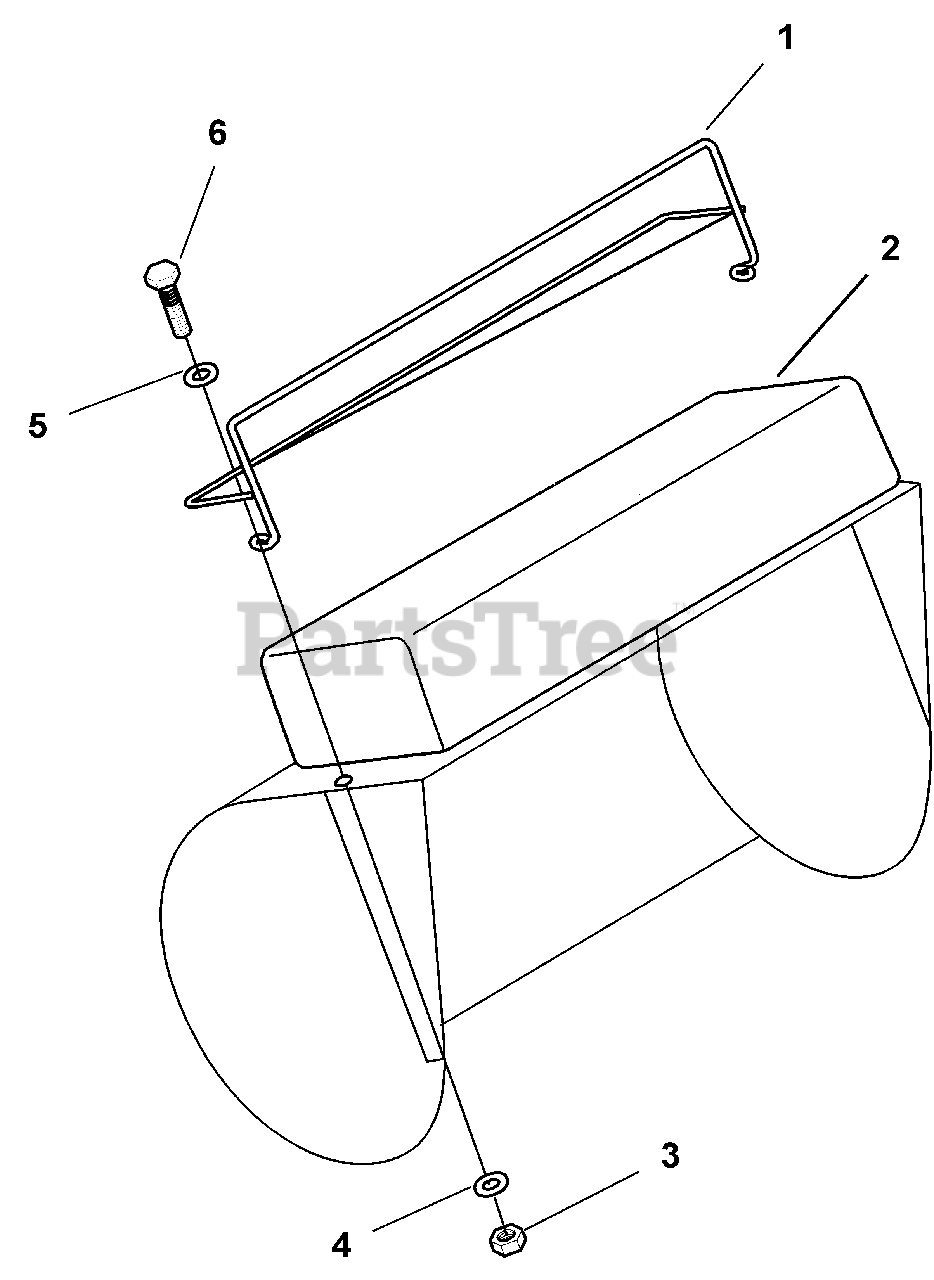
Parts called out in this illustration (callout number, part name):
1	WEIGHT RACK
3	NUT, Hex, 1/4-20
4	LOCKWASHER, 1/4
5	WASHER, 1/4
6	CAPSCREW, Hex Head, 1/4-20 x 1
